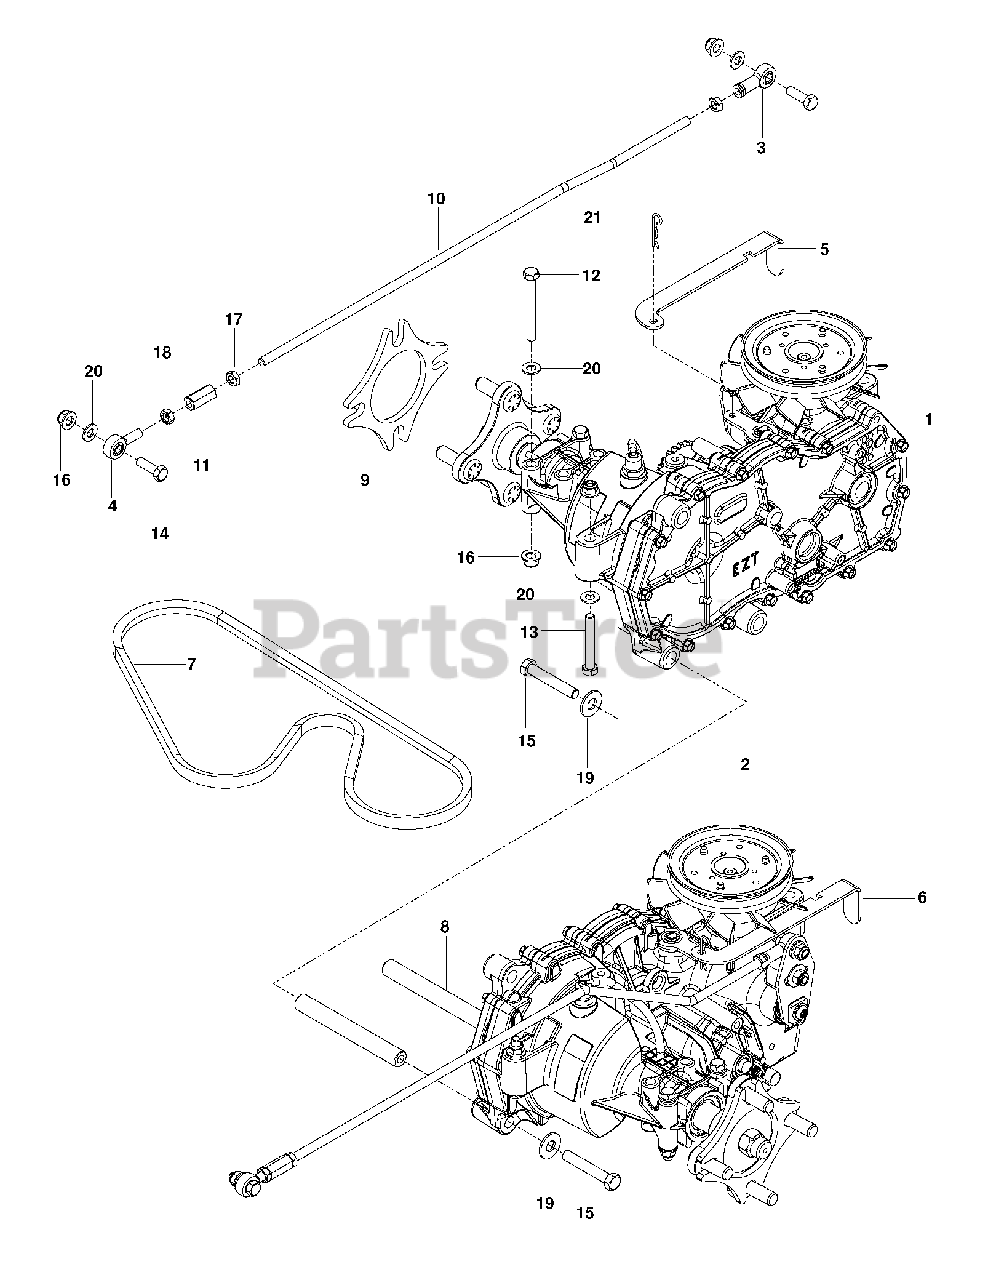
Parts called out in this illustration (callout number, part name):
1	HG_HYDRO RH
2	HG_HYDRO LH
3	RH ROD END
4	RB ROD.END.LH
5	RELEASE LEVER RH
6	RELEASE LEVER LH
7	BELT 30 ZEZT
8	HYDRO SPACER
9	SPACER, WHEEL
10	CONTROL ROD
11	ROD END COUPLER
13	BOLT.FIN HEX 5/16-18UNC X2 1/4
14	BOLT.FIN.HEX.5/16-18UNC X 1.00
15	BOLT.HEX
16	5/16-18 NYLOC FLANGE NUT
17	NUT 5/16-24 UNF HEX JAM
18	NUT 5/16F LEFTHAND
19	WASHER 3/8 FLAT
20	WASHER
21	HAIRPIN #2
